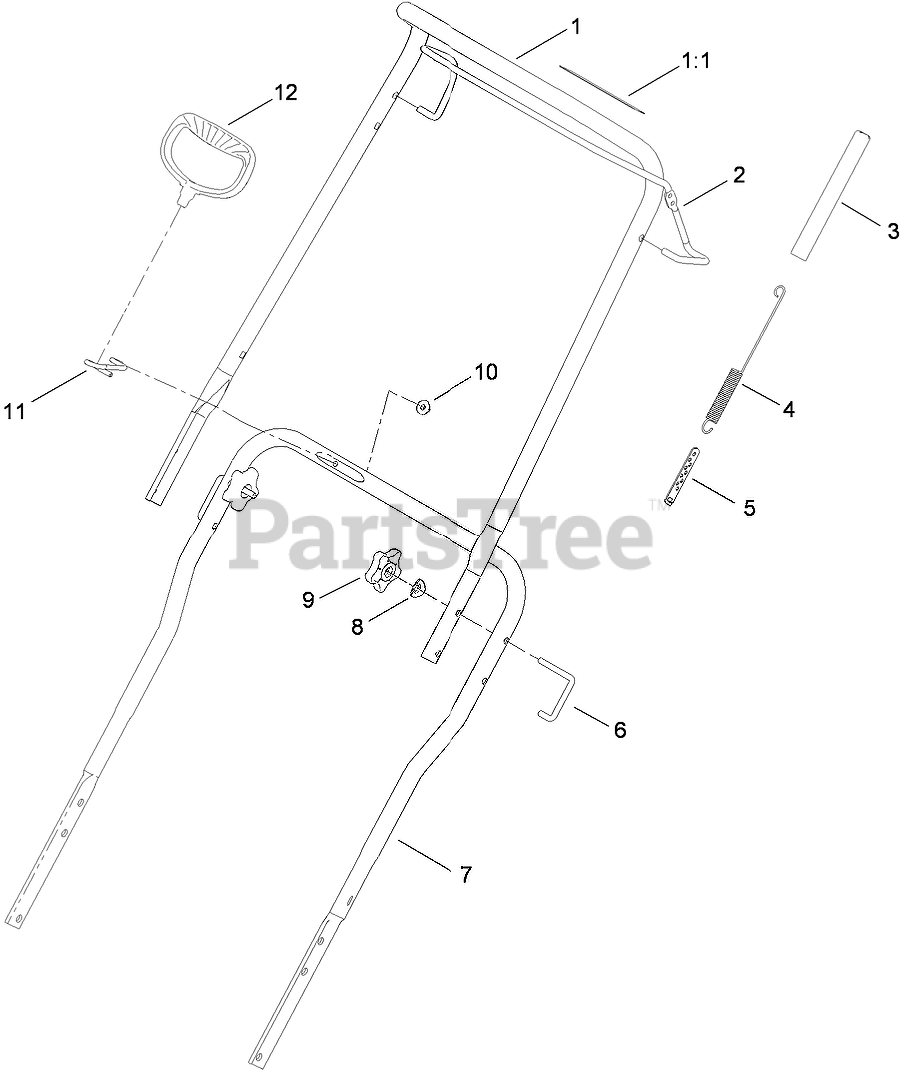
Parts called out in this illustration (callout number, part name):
1	UPPER HANDLE ASM
1:1	DECAL-DRIVE, ROTOR
2	BAIL-CONTROL
3	COVER-SPRING
4	SPRING-EXTENSION
5	ADJUSTER-CABLE, CLUTCH
6	LOCK-HANDLE
7	HANDLE-LOWER
8	WASHER
9	KNOB-HANDLE
10	NUT-HEX FLG
11	GUIDE-ROPE
12	HANDLE-RECOIL
